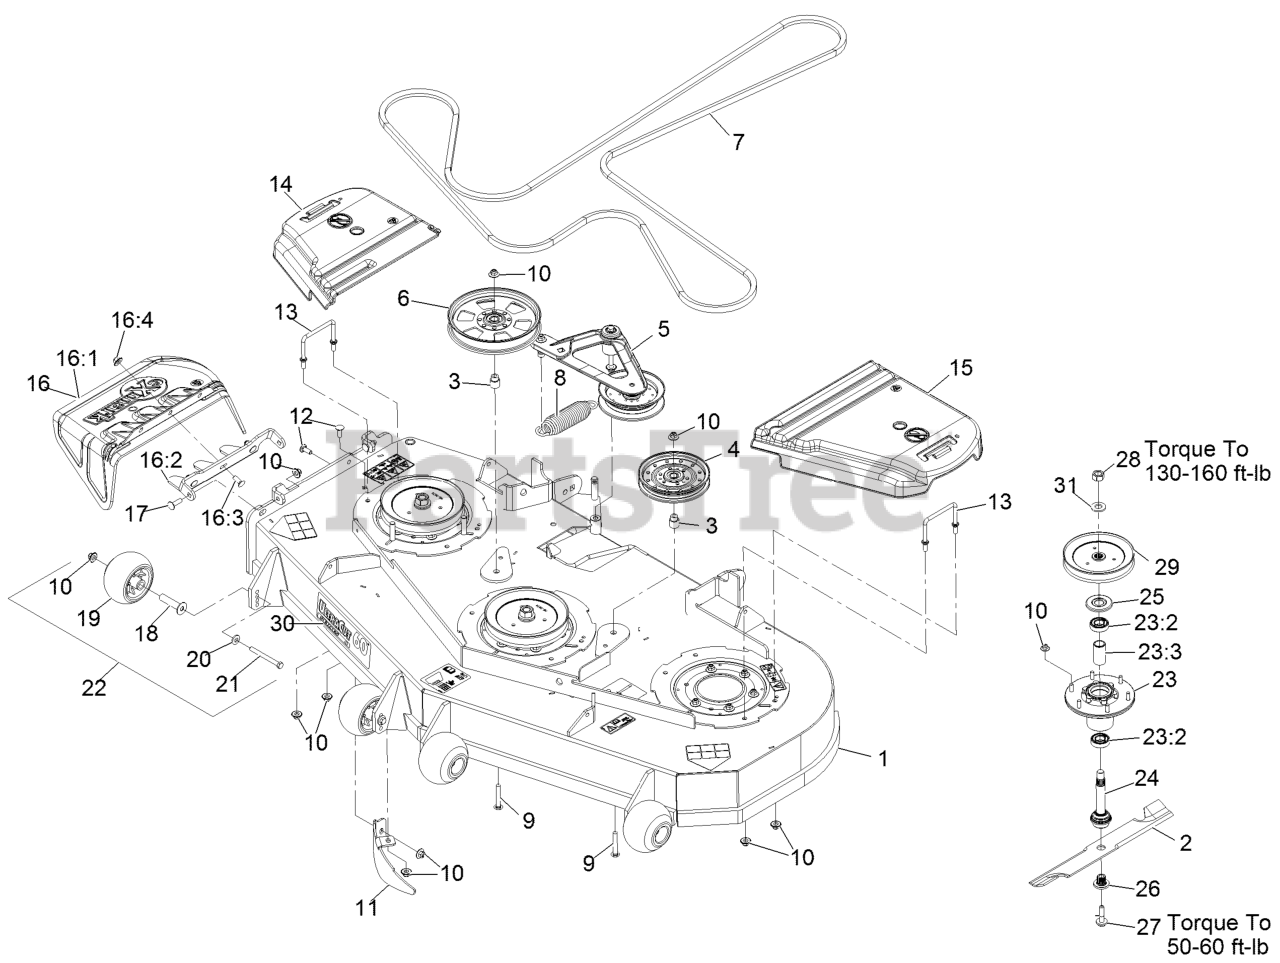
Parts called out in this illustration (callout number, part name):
1	DECK ASM,W/DECALS 60
2	Blade-Extreme 2, 20.50"
3	BUSHING-IDLER
5	DECK IDLER ASM
6	PULLEY-IDLER, FLAT
7	BELT,V-5V-198.75
8	SPRING-EXTENSION
9	SCREW-CARR
10	Nut-Nyloc 3/8-16 Flg
11	DOGLEG - LZ60
12	SCREW-CARR
13	WIREFORM-COVER
14	COVER-BELT, RH
15	COVER-BELT, LH
16	ASM,DISCHARGE CHUTE
16:1	CHUTE,DISCHARGE
16:2	BRACKET,DISCHARGE CHUTE
16:3	SCREW-CARR
16:4	Nut-Nyloc 3/8-16 Flg
17	Bolt-Carriage 3/8-16 X 1 1/4
18	AXLE, ROLLER
19	ROLLER-SCALP, ANTI
20	WASHER-BELLEVILLE
21	SCREW-HH 3/8-16 X 3 3/4 GR 8
22	KIT, ANTI-SCALP ROLLER
23	ASM-CUTTER HSG WITH BEARINGS
23:2	BEARING-BALL
23:3	SPACER-BEARING
24	ASM-SPINDLE AND SEAL
25	GUARD,BEARING TOP .989
26	BUSHING,SPLINED
27	SCREW,SEMS 1/2-20 X 2.19
28	NUT-HEX
29	SHEAVE,BLADE DRIVE 7.25
30	DECAL,ULTRACUT 60 SERIES
